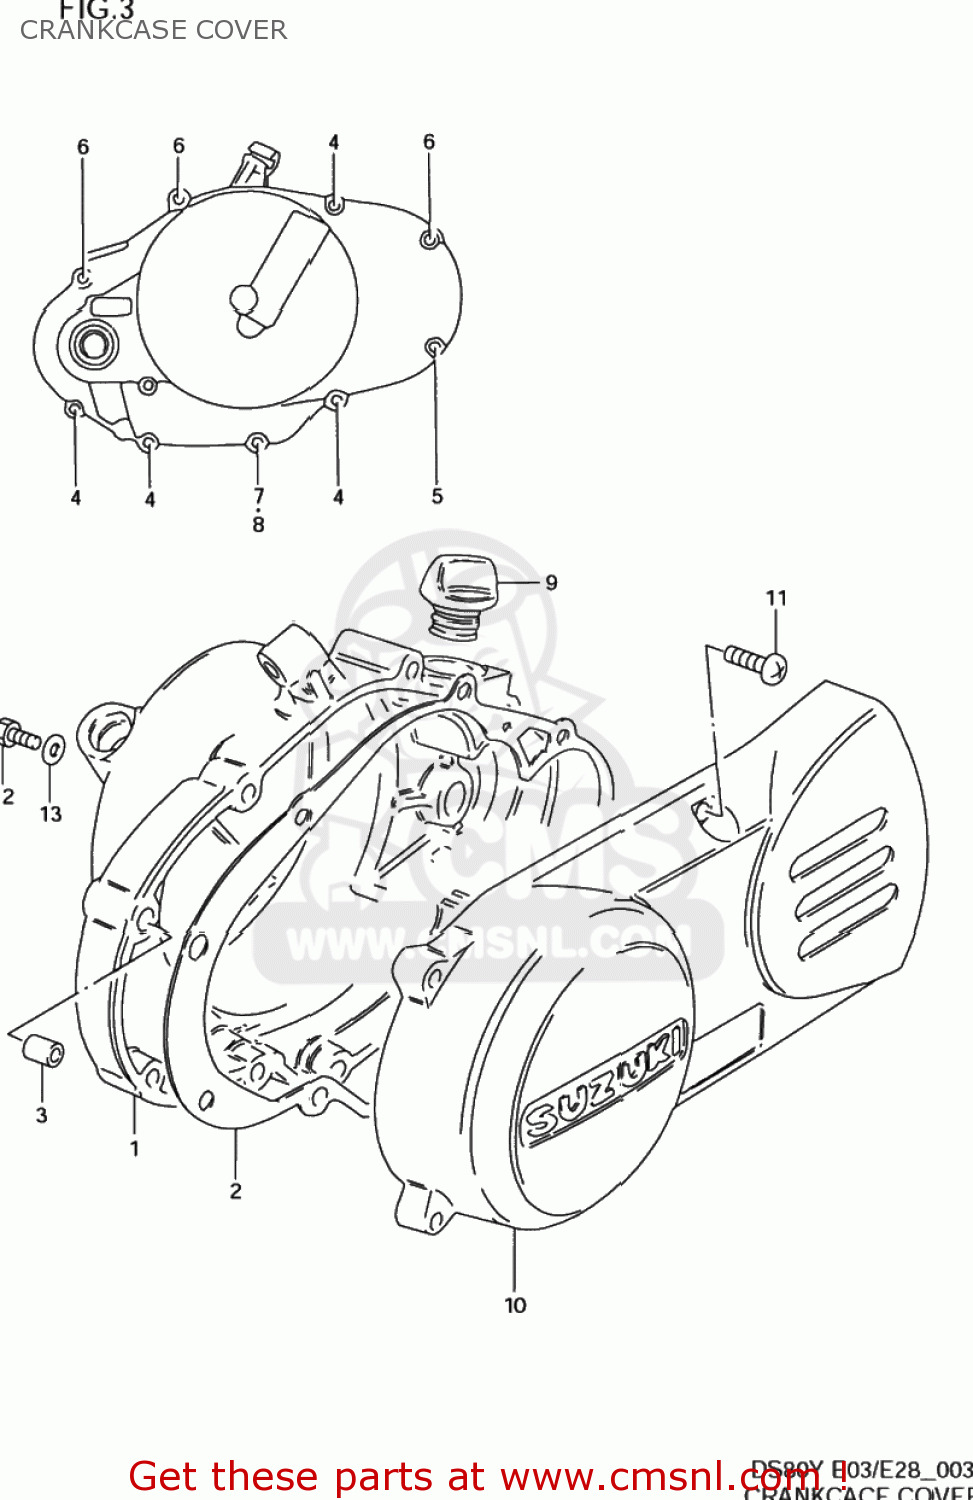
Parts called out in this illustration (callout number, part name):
1	COVER,CLUTCH
2	GASKET,CLUTCH COVER (NAS)
3	PIN
4	SCREW
5	SCREW 6X30
6	SCREW
7	SCREW
8	GASKET(6.2X11X1).2 (NAS)
9	PLUG
10	COVER,MAGNETO
11	SCREW
12	SCREW(6X10)
13	GASKET(6.2X11X1) (NAS)
